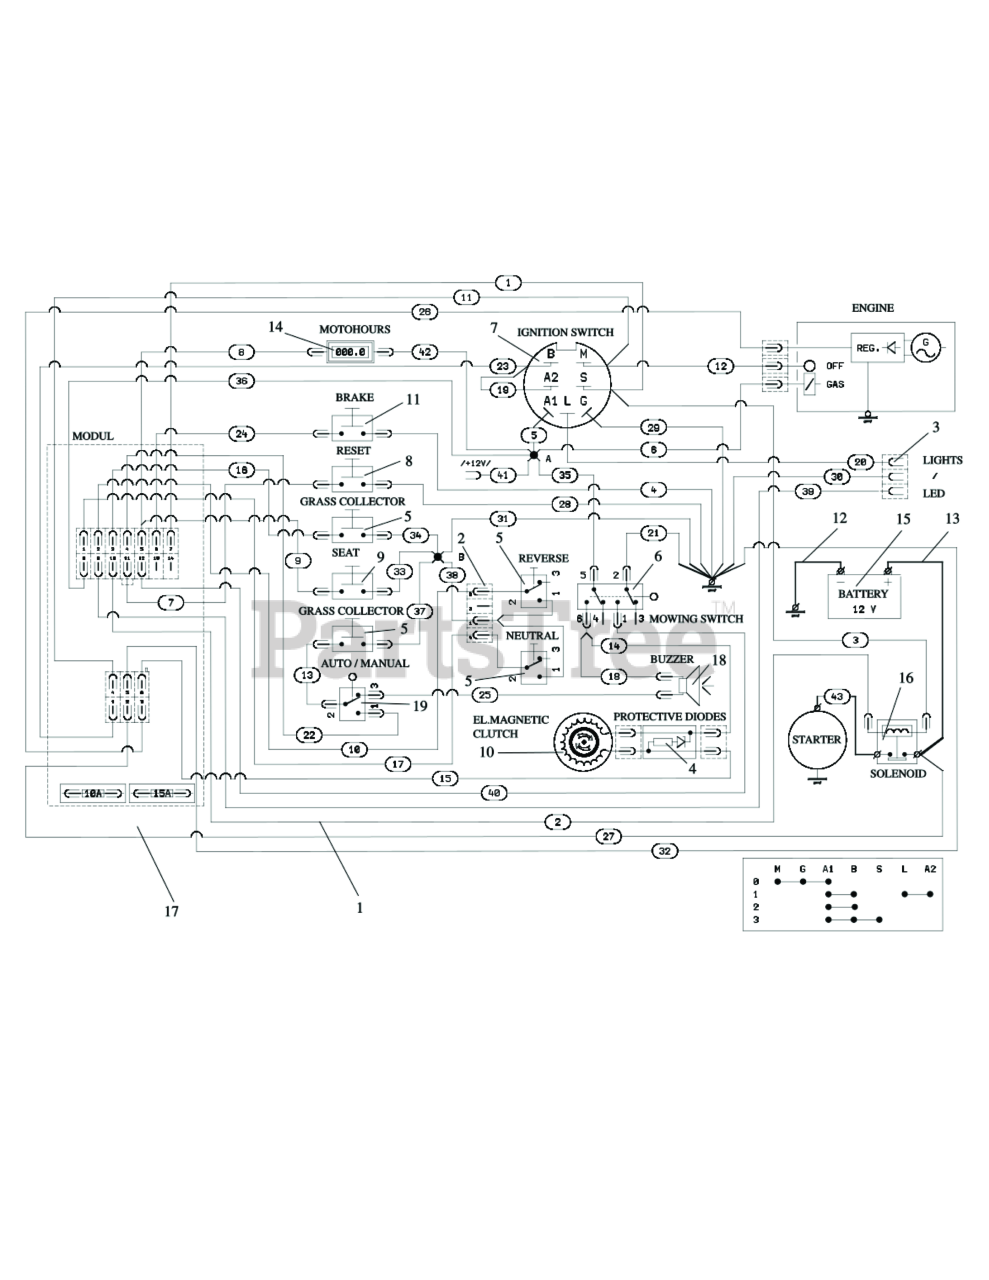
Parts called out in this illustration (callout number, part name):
1	HARNESS, Wiring
5	MICROSWITCH
14	HOURMETER
16	SOLENOID
